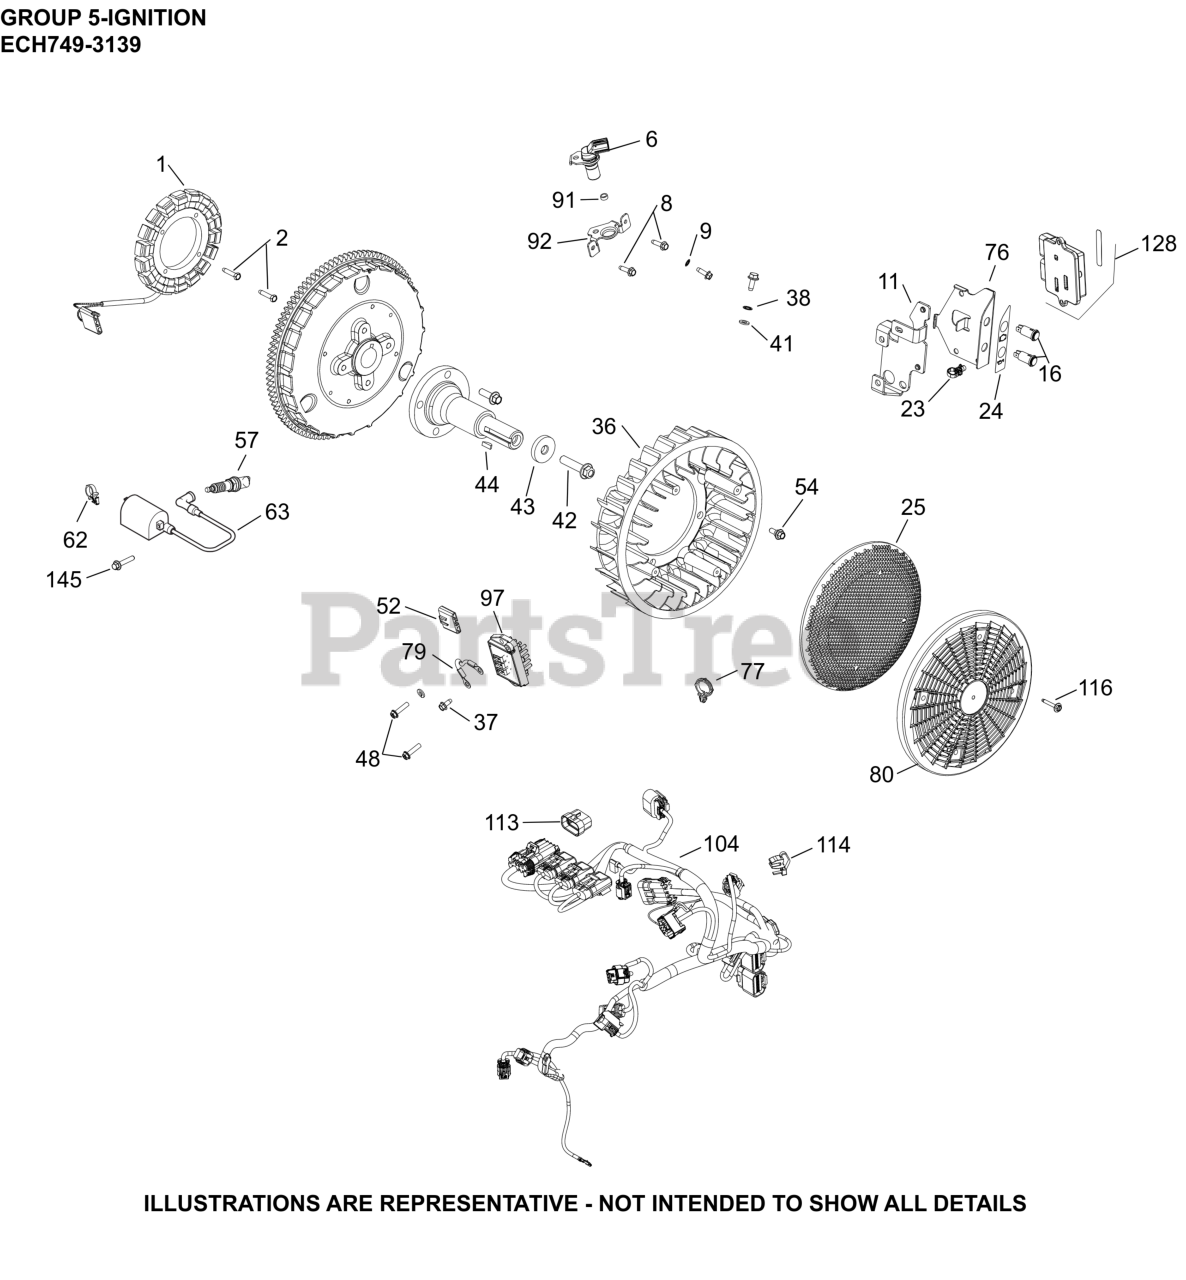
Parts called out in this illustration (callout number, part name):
1	KIT, 15 / 20 AMP STATOR
2	SCREW, THREAD FORMING
3	FLYWHEEL, ASSEMBLY
6	SENSOR, SPEED
8	SCREW, THREAD FORMING
9	WASHER, INT TOOTH LOCK #10
11	BRACKET, ECU
16	LIGHT, INDICATOR
23	TIE, WIRE
24	DECAL, WARNING LIGHT
25	KIT GRASS SCREEN
36	FAN-USE 24 755 253-S
37	SCREW, THREAD FORMING
38	WASHER, INT TOOTH LOCK 1/4"
41	WASHER, FLAT 1/4" (O.D. 1/2")
42	SCREW, HEX FLANGE
43	WASHER, FLAT
44	KEY, 3/16" X 5/8"
48	SCREW, HEX FLANGE HI-LO
52	CONNECTOR
54	BOLT, SHOULDER
57	SPARK PLUG, RFI
63	COIL, IGNITION - EFI (RFI/EMC)
76	BRACKET, WARNING LIGHT
77	RETAINER, WIRE HARNESS
80	SCREEN, GRASS
92	BRACKET, SENSOR
97	REGULATOR, RECTIFIER (20-30AMP,FW W/OVP)
104	HARNESS, WIRING (B-BAY, EFI-ETB)
113	CAP, DIAGNOSTIC (8-WAY)
114	TIE, WIRE EDGE FIXED
116	SCREW, FLG SEMS M4x.7x25
128	MODULE, ECU MT05.3 SERVICE
145	SCREW, HEX FLANGE
